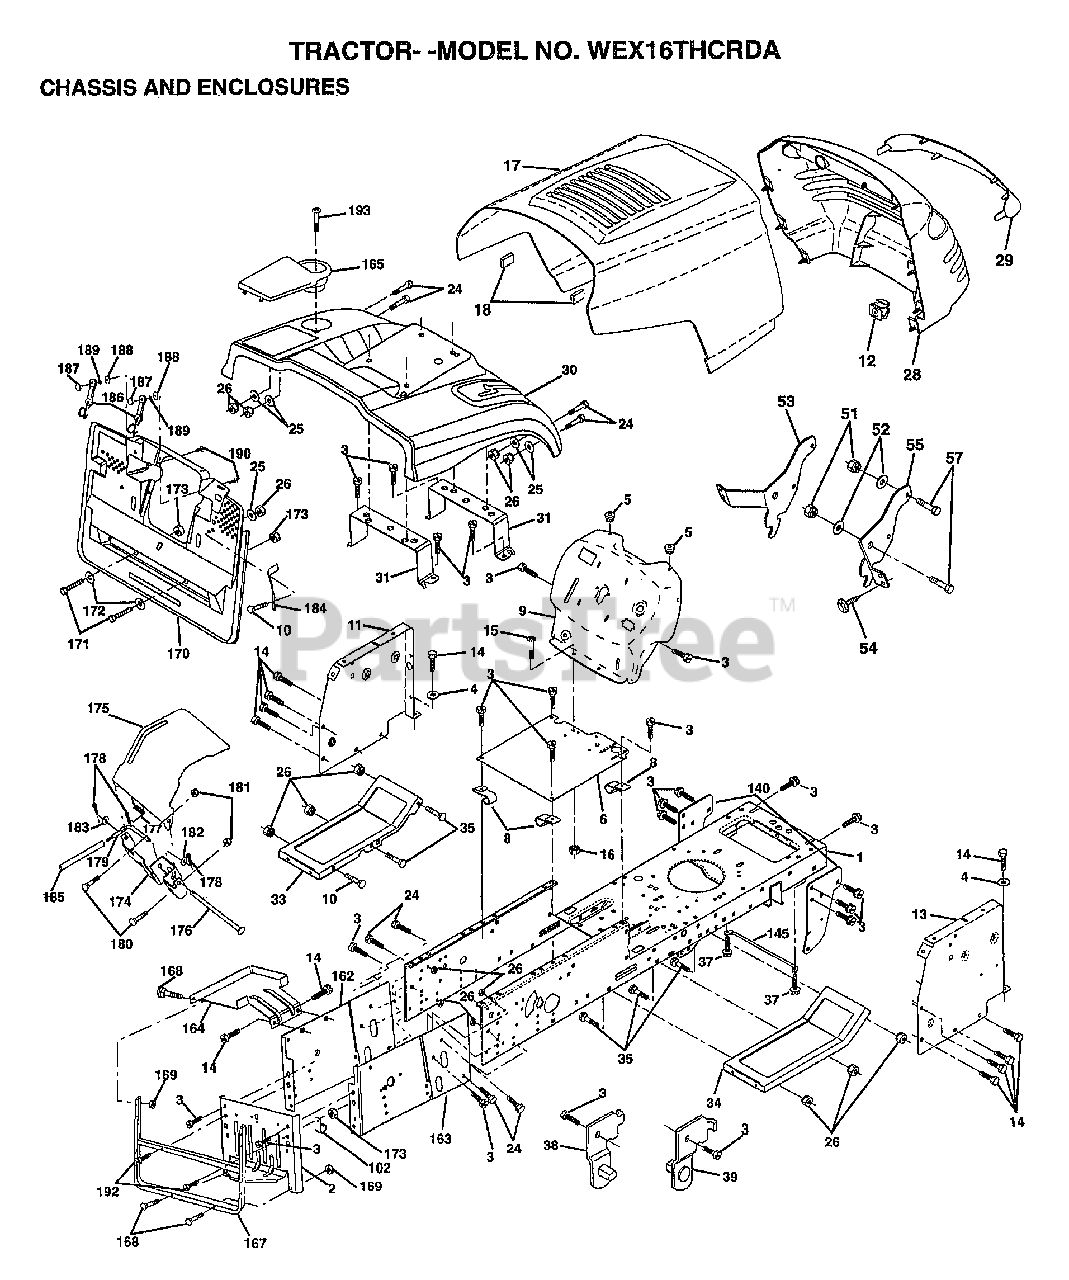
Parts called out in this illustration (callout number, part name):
1	CHASSIS.STAMPING
2	DRAWBAR.CRD
3	SCREW
4	WASHER
5	BUMPER-HOOD/DASH
6	SADDLE
8	"CLIP,INSULATOR"
9	DASH.SILKSCREEN
11	"PANEL-DASH,LH"
12	CLIP.TINNERMAN
14	SCREW LT
15	SCREW
17	HOOD.STEEL.ASSY
20	"PLATE-MTG,BATT/FU"
24	BOLT
25	WASHER
26	NUT
28	GRILLE-MS428
29	LENS.GRILLE.PRIVATE LABEL
30	FENDER.CRD.GREEN
31	BRKT.SUPT.FENDER.CRD
33	FOOTREST.LH.LT/GT
34	FOOTREST.RH.LT/GT
35	BOLT
37	SCREW LT
38	BRACKET ASM LH
39	BRACKET ASM RH
51	NUT
52	WASHER
53	BRACKET.GRILLE.LH
54	SCREW.HEX.WS.HD
55	BRACKET.GRILLE.RH
58	AIR DUCT
102	CLIP T
125	SCREW
140	BRKT SUSPENSION
145	"ROD POVOT,CHASSIS"
148	SCREW
162	BRKT.EXT.CHASSIS.LH.CRD
163	BRKT.EXT.CHASSIS.RH.CRD
164	SUPPORT.BATTERY.CRD
165	COVER.BATTERY.CRD.BLACK.LT
167	SUPT.ASM.BACKPLATE
168	BOLT-RD HD SQ NK
170	COVER.BACKPLATE.BLACK
171	BOLT.HEX.3/8-16X2-1/2
173	NUT
174	BRKT.SWITCH.FBI.CRD
175	GRUARD.DOOR.REAR.CRD
176	HINGE PIN
177	SPRING.COVER.LH
179	ROD.PIVOT.FBI.CRD
182	WASHER.385X.625
183	WASHER
184	BRKT.ACTUATOR.BAG.CRD
185	TUBE.LEVER.SWCH.FBI.CRD
186	LATCH ASSY.BAGGER
187	WELDNUT
188	WASHER #10
189	LOCKWASHER
190	SCREW
192	SCREW LT
193	SCREW LT
